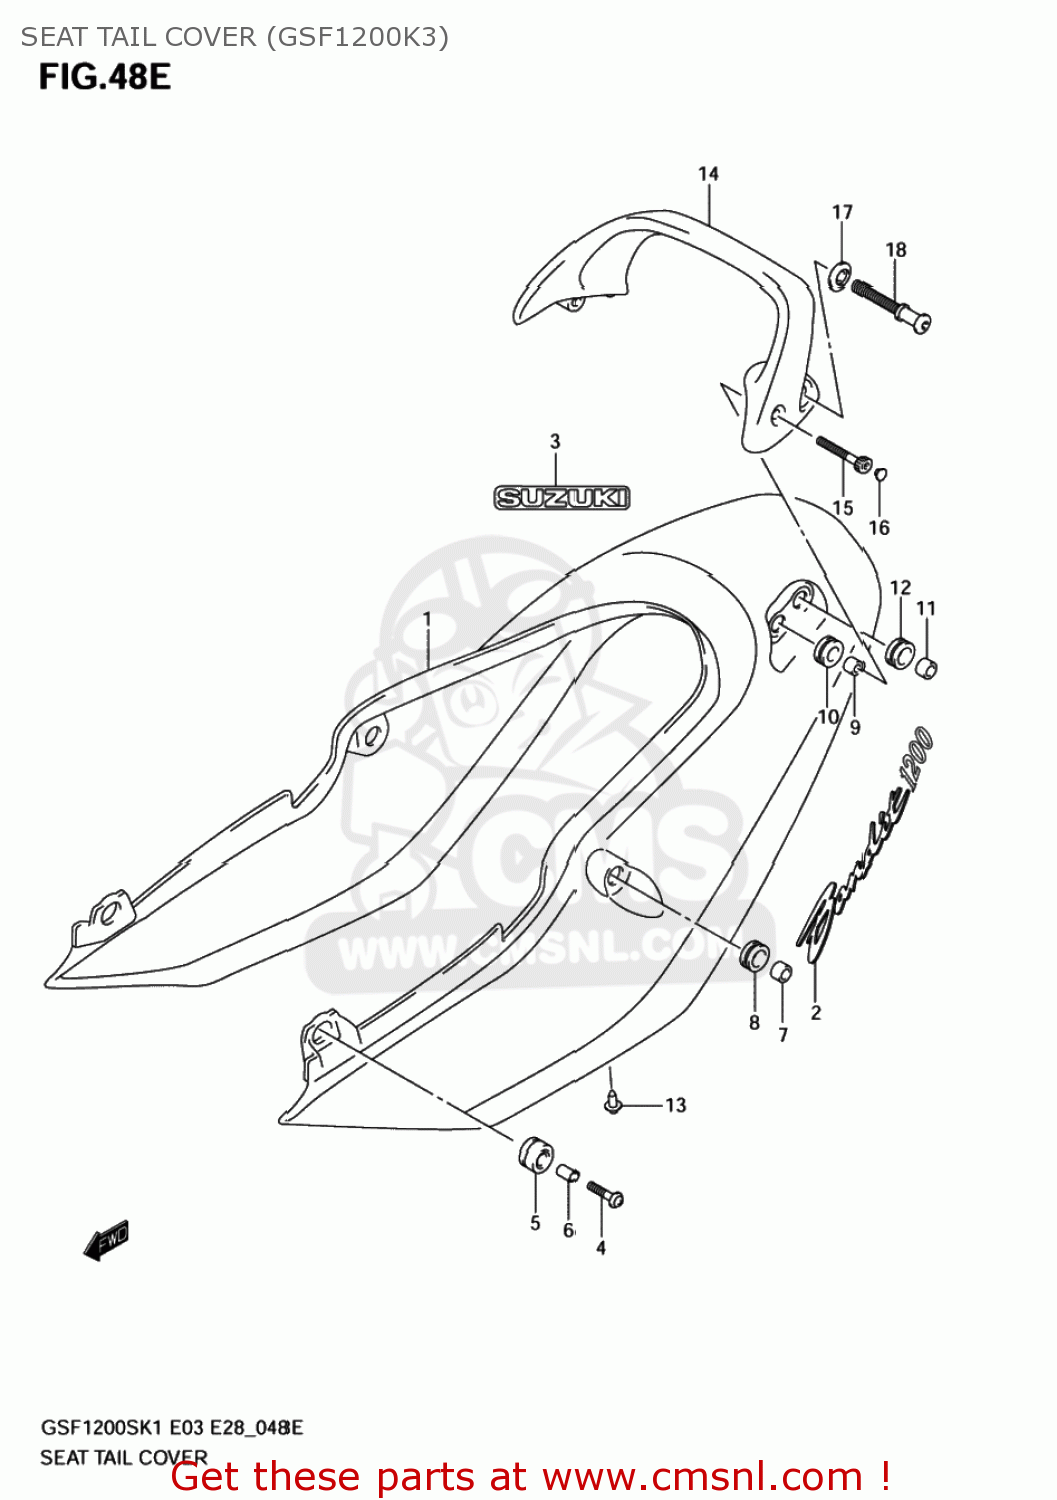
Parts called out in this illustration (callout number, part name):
1	COVER,SEAT TAIL
2	EMBLEM,SEAT TAIL COVER
3	EMBLEM,SUZUKI
4	SCREW(6X30)
5	CUSHION,SEAT TAIL COVER FR
6	SPACER(6.5X10X13)
7	SPACER,8.5X14X9
8	CUSHION
9	SPACER(6.5X12X9)
10	CUSHION
11	SPACER,8.5X14X9
12	CUSHION
13	CLIP(BLACK)
14	HANDLE,PILLION RIDER
16	CAP(OD:10)
17	WASHER,HOOK
18	HOOK,PILLION RIDER HANDLE
